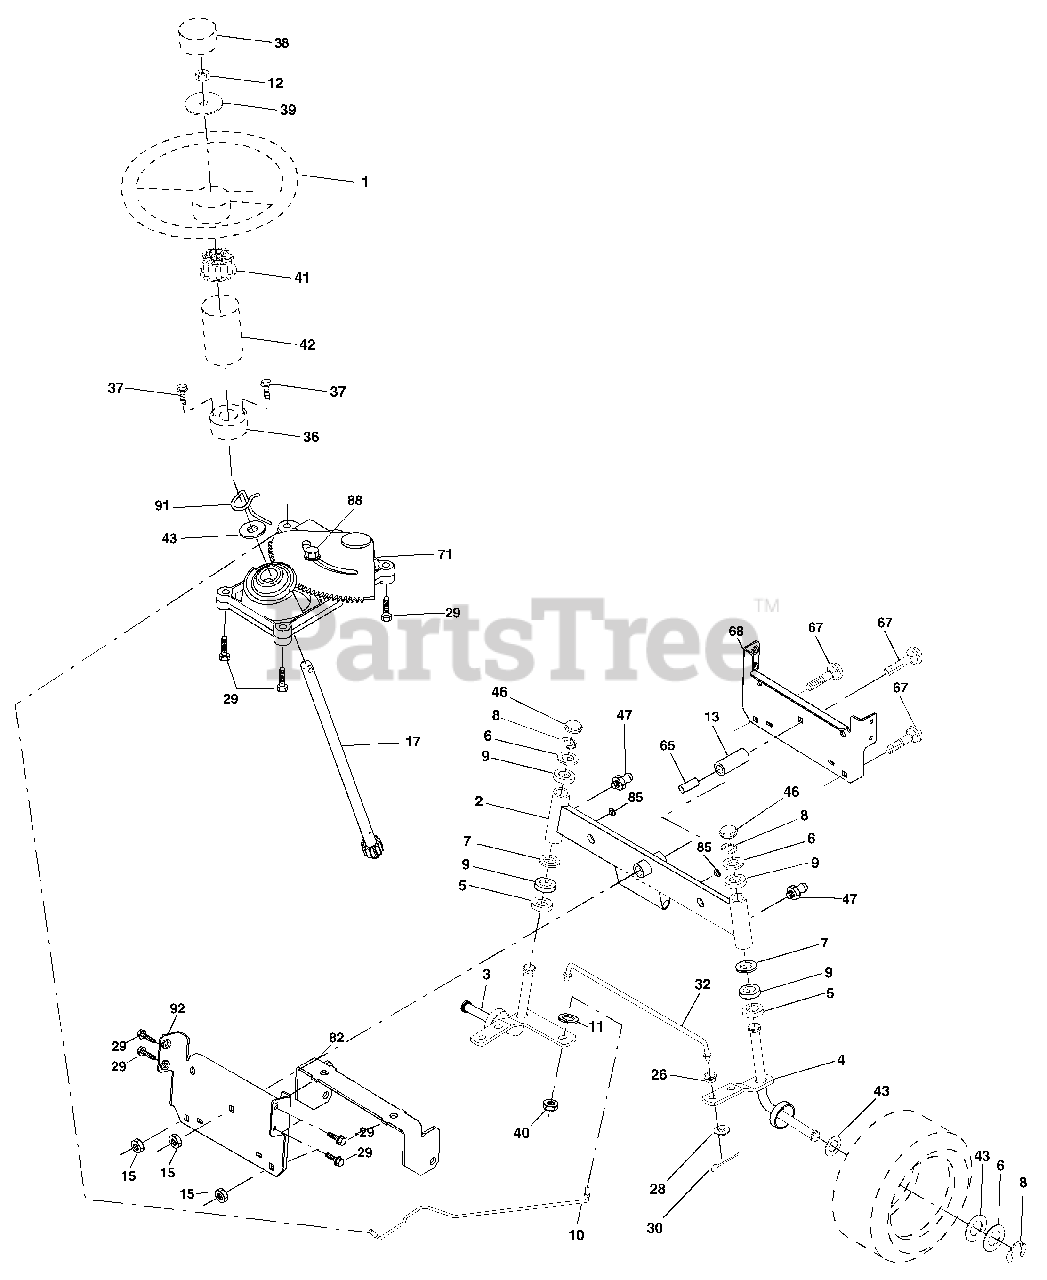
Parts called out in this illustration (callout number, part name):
1	Wheel Steering Auto Black
2	Axle Asm Front
3	Spindle Asm Lh
4	Spindle Asm Rh
5	Bearing Race Thrust Harden
6	Washer 25/32 X 1 5/8 X 16ga
7	Washer 27/32 X 1 1/4 X 16 Ga
8	Ring Klip #t5304-75
9	Bearing Col Strg Blk
11	Lockwasher
12	Nut Hex Jam Toplock 1/2-20 Unf
13	Spacer Bearing Axle Front
15	Nut Hex Flange Lock
17	Shaft Asm Strg
26	Bushing Rod Tie Blk Lt
28	Washer 13/32 X 7/8 X 16ga
29	Screw 3/8-16x3/4
30	Pin
32	Rod Tie Wire Form 19 75 Mech
36	Bushing Strg
37	Screw TT #10-32 x 5 x 3/8 Flange
38	Insert Cap Strg
39	Washer .53 x 2.25 x .160 Zinc
40	Locknut Center
41	Adaptor Wheel Strg 640/ 635id
42	Boot Dash Steering
43	Washer 25/32 X 1 1/4 X 16 Ga
46	Cap Spindle Fr Top Blk
47	Fitting Grease
65	Spacer Axle
67	Bolt Rdhd Sq 3/8-16 Unc x 2-1/4
68	Brace Axle Front
71	Steering Asm
82	Bracket Susp Chassis Front
85	Fastner Christmas Tree
88	Bolt Shoulder 7/16-20
91	Clip Steering
92	Axle Rear 16" Tires GTV
